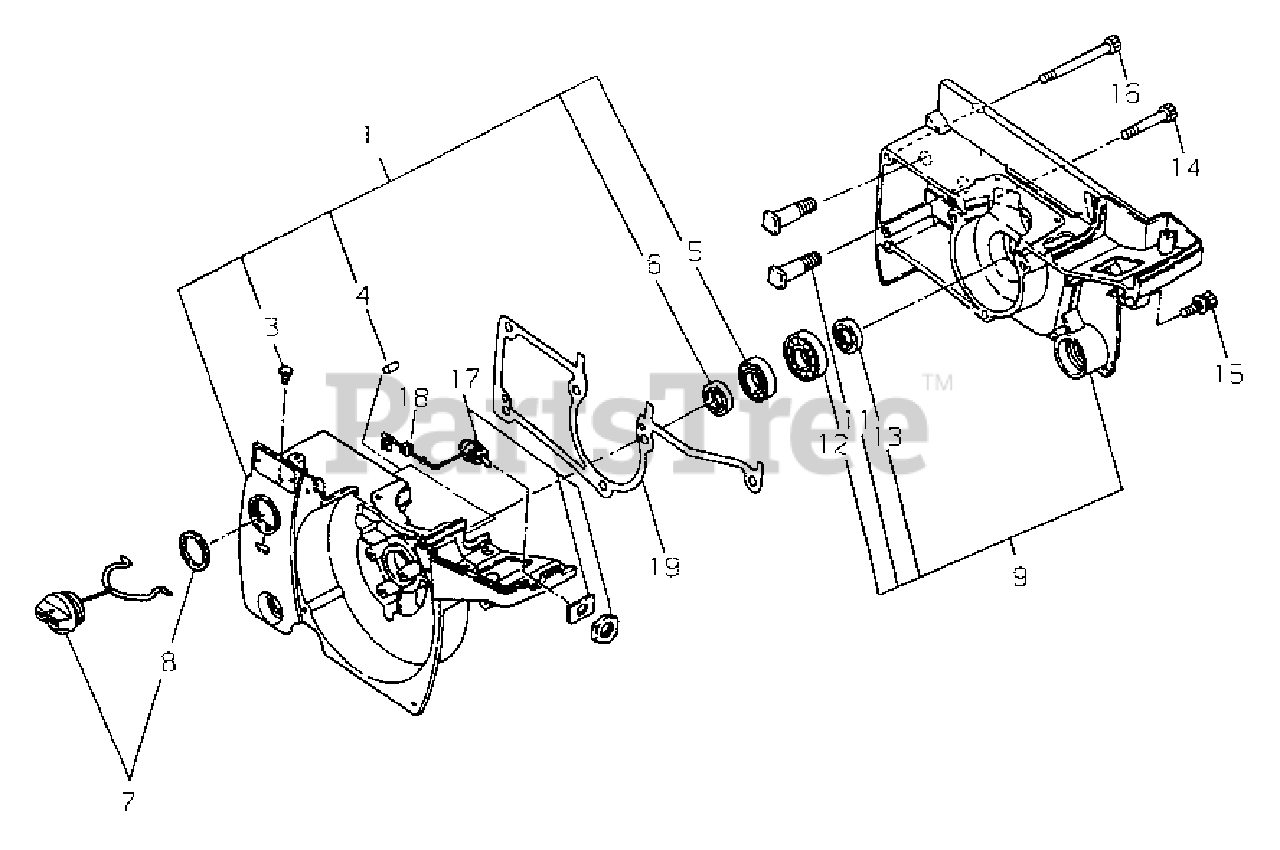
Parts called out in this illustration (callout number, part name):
1	CRANKCASE ASSY - LEFT
3	VALVE, OIL
4	PIN - LOCATING
5	BEARING, BALL - 6001C3
6	SEAL, OIL
7	CAP ASSY
8	GASKET
9	CRANKCASE ASSY - RIGHT
11	BOLT, BAR
12	BEARING, BALL - 6201C3
13	SEAL, OIL
14	SCREW - 5X30
15	SCREW - 5X18
16	SCREW - 5X45
17	IGNITION SWITCH ASSY
19	GASKET, CRANKCASE
